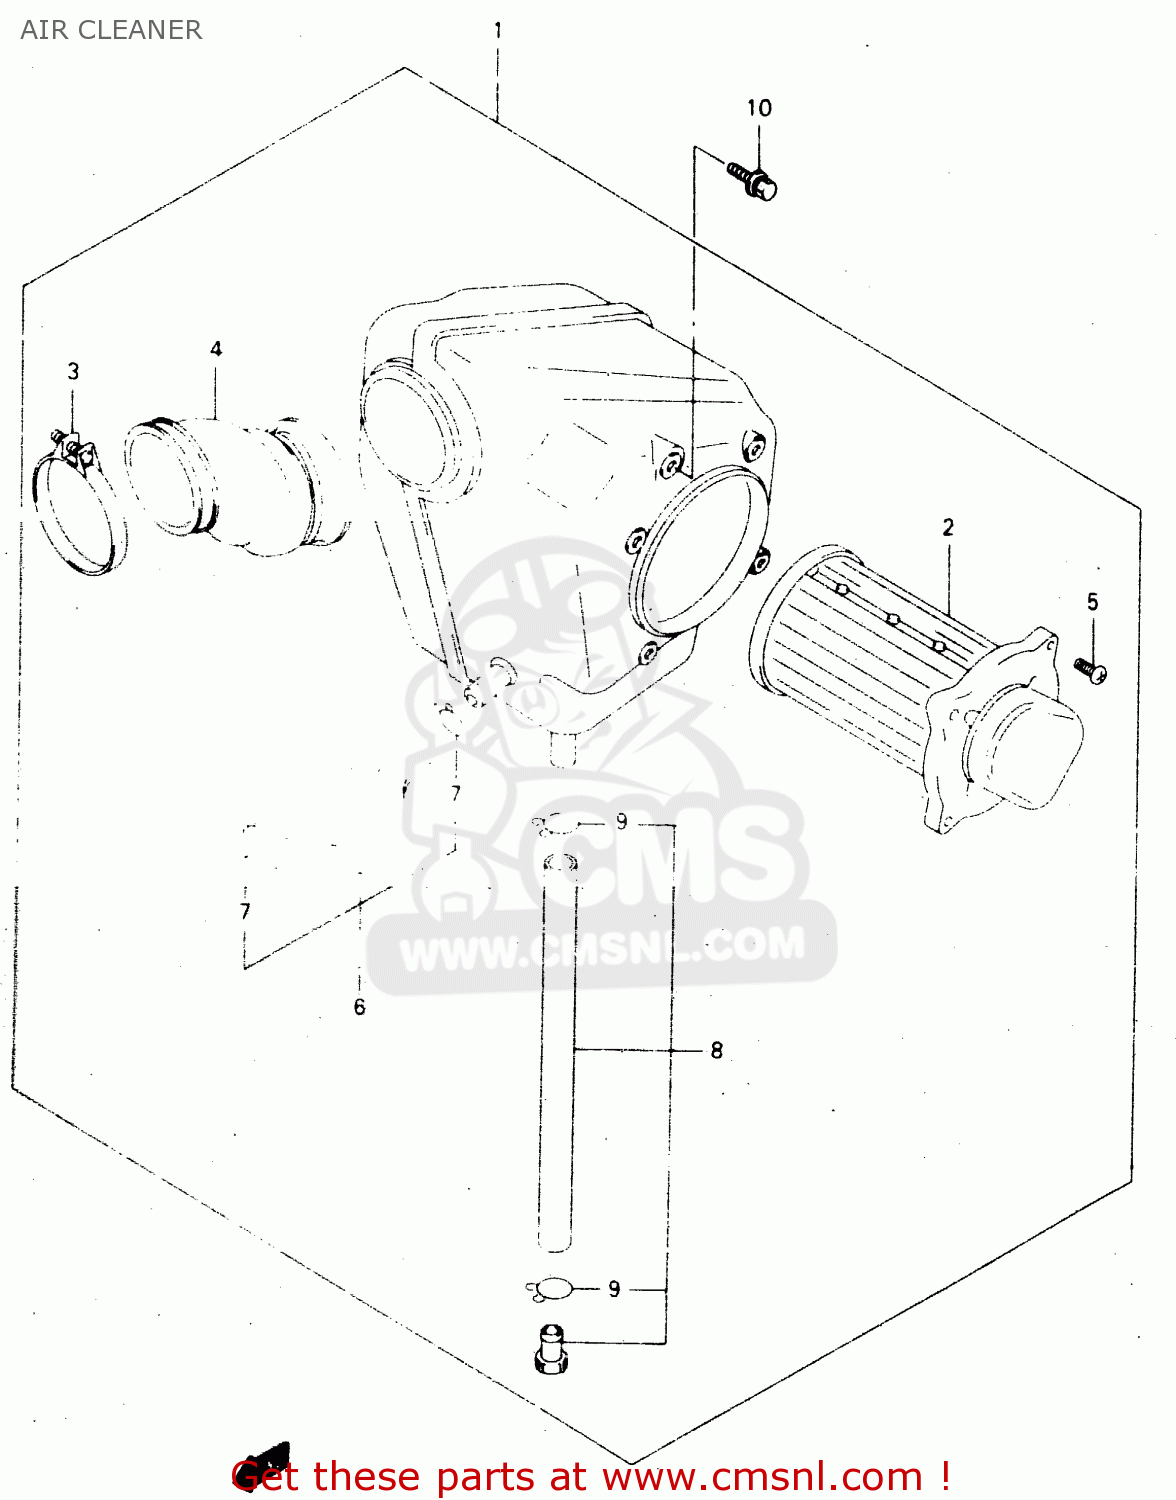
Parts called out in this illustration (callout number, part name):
1	CLEANER ASSY,AIR
2	FILTER,AIR CLEANER
3	CLAMP
4	TUBE,OUTLET
5	SCREW
6	TUBE,BREATHER
7	CLIP
8	TUBE,DRAIN
9	CLIP
10	BOLT
